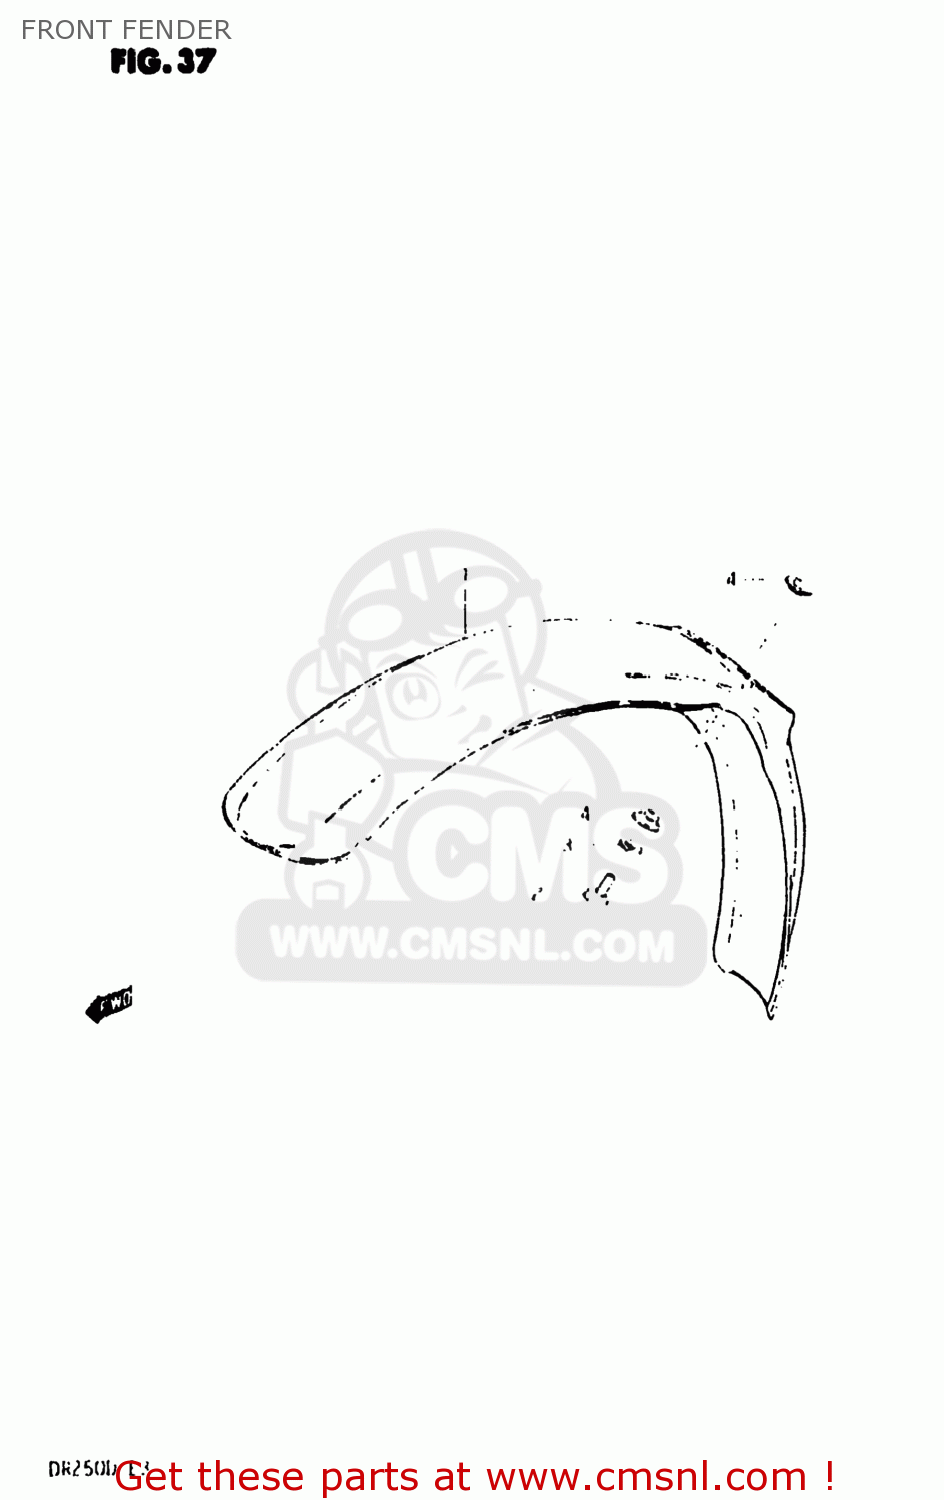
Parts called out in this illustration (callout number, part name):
1	FENDER,FRONT
2	BOLT, UPPER
3	LOCK WASHER
4	SPACER
